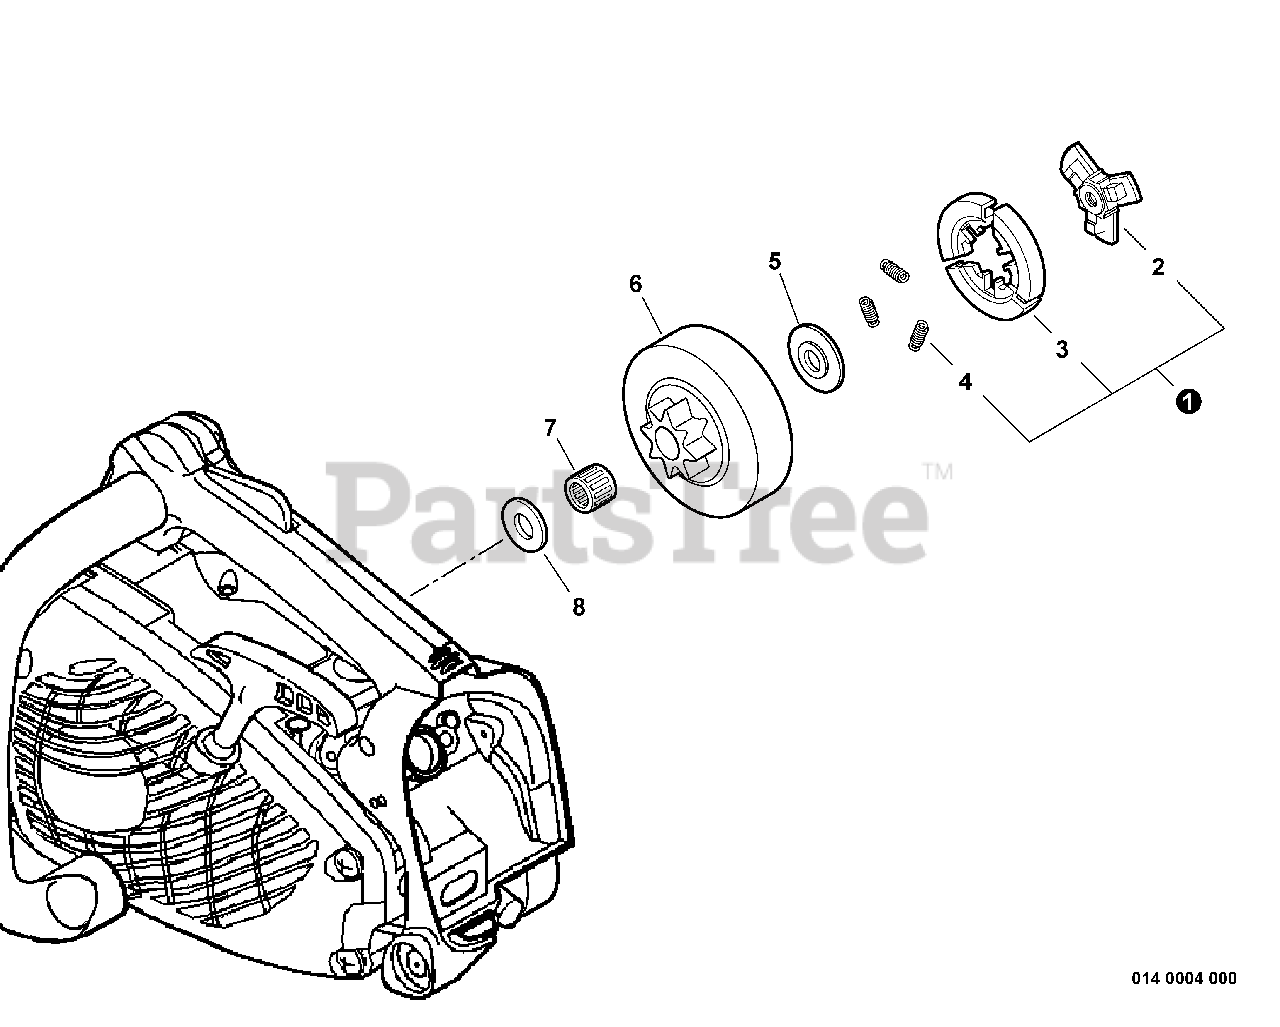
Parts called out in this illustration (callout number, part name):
1	CLUTCH ASSY
2	HUB, CLUTCH
3	CLUTCH SHOE SET
4	SPRING, CLUTCH
5	PLATE, CLUTCH
6	DRUM, CLUTCH
7	BEARING, NEEDLE
